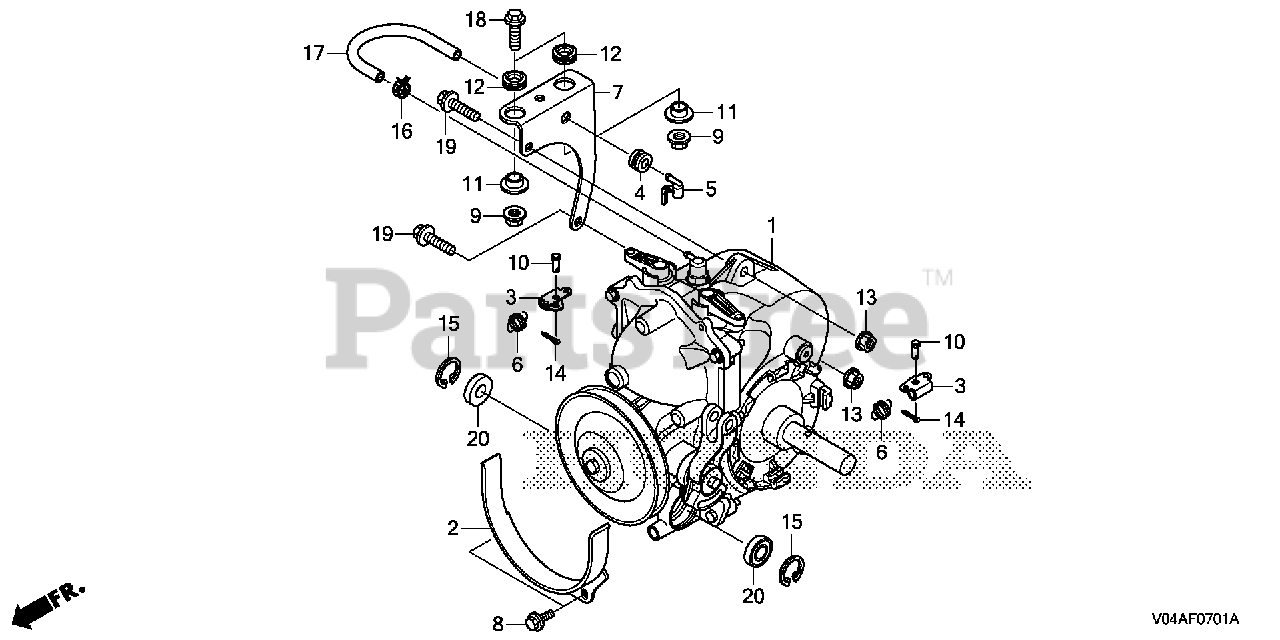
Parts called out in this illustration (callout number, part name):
1	TRANSMISSION ASSY.
2	GUIDE, BELT
3	ARM, CHANGE LEVER
4	RUBBER, MOUNTING
5	CAP, WATER PROTECTION
6	SPRING, RETURN
7	PLATE, TRANSMISSION MOUNT
8	BOLT, FLANGE (6X12) (CT200)
9	NUT, FLANGE (8MM)
10	PIN, CLEVIS (6.3X17)
11	COLLAR, TRANSMISSION MOUNTING
12	GROMMET, ENGINE BED
13	NUT, FLANGE (8MM)
14	PIN, COTTER (3.0X18)
15	CIRCLIP (INNER) (32MM)
16	CLIP, TUBE (D8)
17	BULK HOSE, VACUUM (4.5X1000) (4.5X290)
18	BOLT, FLANGE (8X22)
19	BOLT, FLANGE (8X28) (NOT AVAILABLE)
20	BEARING, RADIAL BALL (6002UU)
